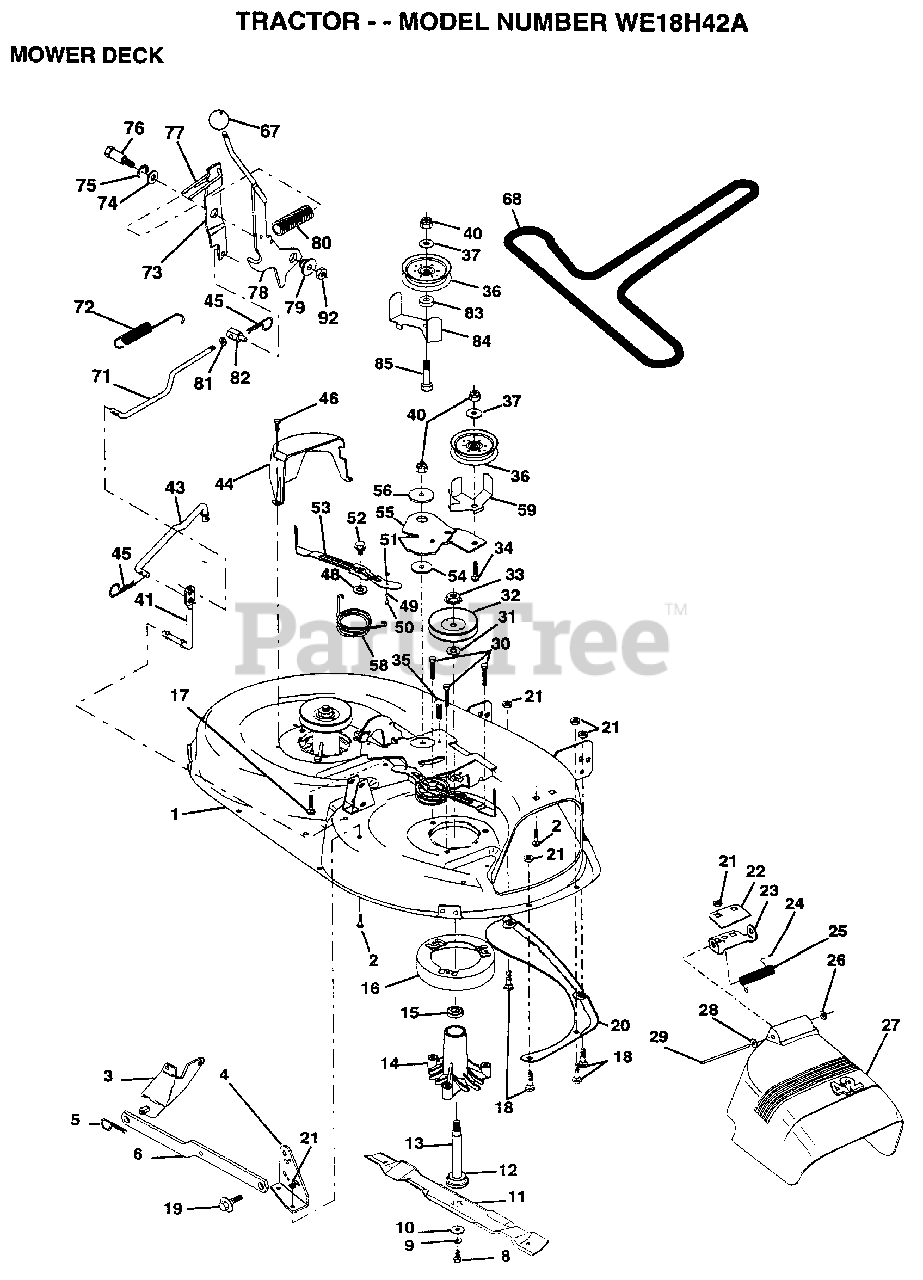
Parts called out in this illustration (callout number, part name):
1	DECK.WELD.42.
2	BOLT
3	BRKT ASM SWAY BAR
4	BRKT DECK SW BAR
8	BLADE BOLT
10	WASHER.HARD.BLADE
11	"BLADE.42"" HIPERF"
12	BEARING.BALL
14	HSG ASM MANDREL
15	BEARING
16	STRIPPER RND MWR
17	BOLT RDHD 3/8-16
18	BOLT
19	BOLT SHD 5/16-18
22	STIFFENER BRKT
23	DEFLECTOR BRKT
24	CAP-SLEEVE LT
25	SPRING TORSION
26	NUT PUSH M
27	DEFLECTOR.SHIELD
28	WASHER
29	HINGE ROD
31	WASHER
34	BOLT
35	XMAS TREE FASTNER
36	FLAT IDLER PULLEY
37	WASHER
41	PIVOT ROD
43	ROD CLUTCH W/NIBS
44	GUARD MAND LH BLK
45	RETAINER M
46	SCREW.1/4-20X5/8
48	HARD SMALL WASHER
50	SHOULDER BOLT
51	LOCKNUT
52	BOLT.SHLD.5/16-18
53	BRAKE PAD ARM ASM
54	HARDENED WASHER
56	SPACER RETAINER
58	SPRING TORSN BRAK
59	GUARD IDLER TUV
67	KNOB T (1/2-HOLE)
68	BELT.V.T-PATH
71	ROD CLUTCH 38/42
72	SPRING.EXT.RETURN
73	CLUTCH ARM SECOND
74	WASHER
75	RING
76	SHOULDER BOLT
77	SPRING KEEPER
79	BUSHING
81	NUT
82	TRUNION ADJ
83	WASHER
85	BOLT RDHD 3/8-16
